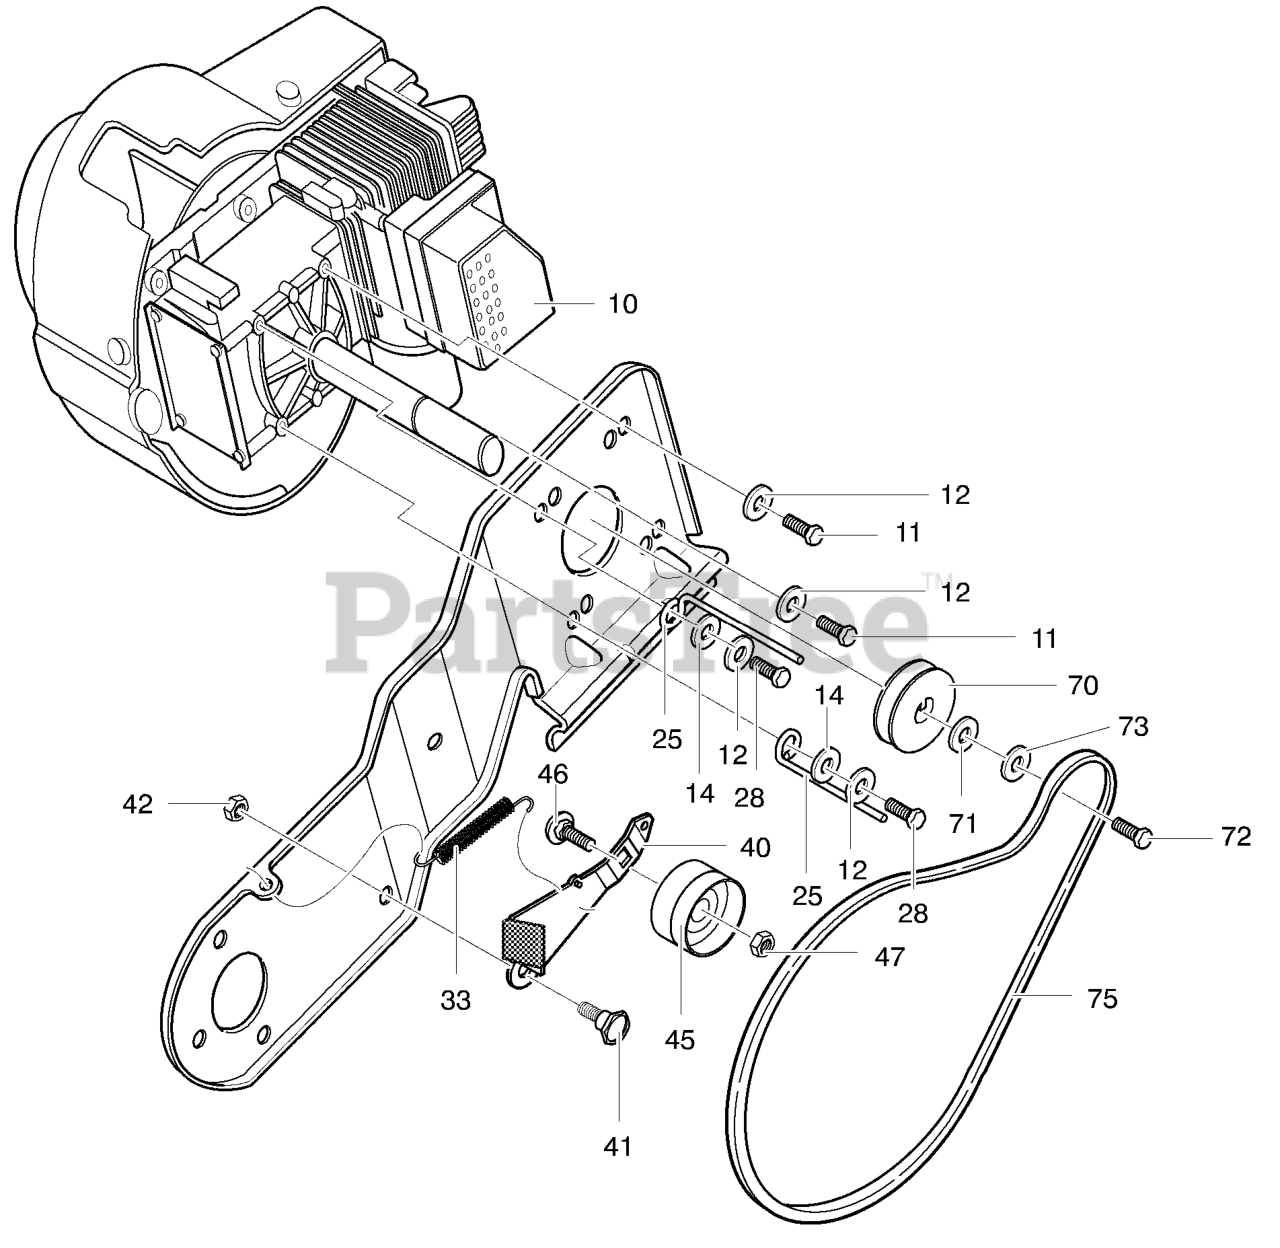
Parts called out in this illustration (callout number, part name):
10	5 HP ENGINE
11	SCREW, 5/16-18 x 0.75
12	WASHER
14	FLATWASHER
25	BELT GUIDE
28	SCREW, 5/16-18 x 1.00
33	SPRING, IDLER BRAKE
40	IDLER ARM
41	BOLT, 5/16-18
42	NUT,5/16-18
45	PULLEY, IDLER
46	BOLT, 3/8-16X1.50
47	NUT, 3/8-16 JAM
71	WASHER
72	SCREW, 5/16-24 x .75
73	WASHER
